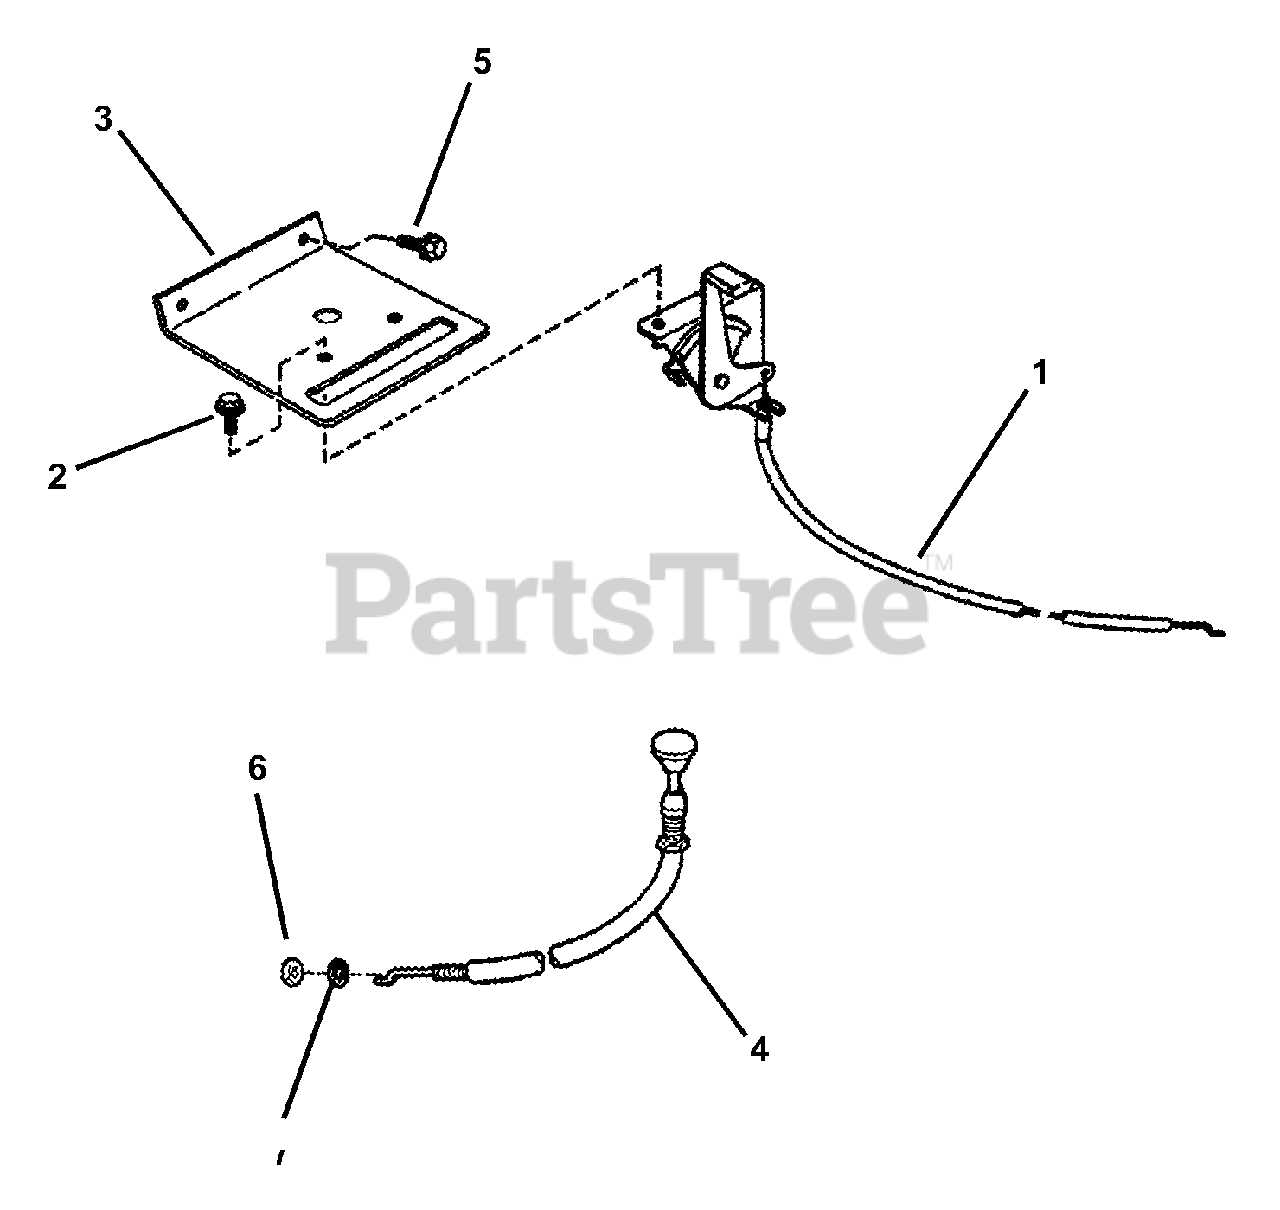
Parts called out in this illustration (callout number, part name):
1	CONTROL, Throttle (33.6" long) (Briggs Engines)
2	SCREW, #10-24 x 1/2" Hex Washer Self-Tap (Torx)
3	PLATE, Throttle Control
4	CONTROL, Choke
5	SCREW, 1/4-20 x 5/8" Self-Tap
6	NUT, 3/8-24 Hex
7	WASHER, 3/8" Internal Tooth Lock
